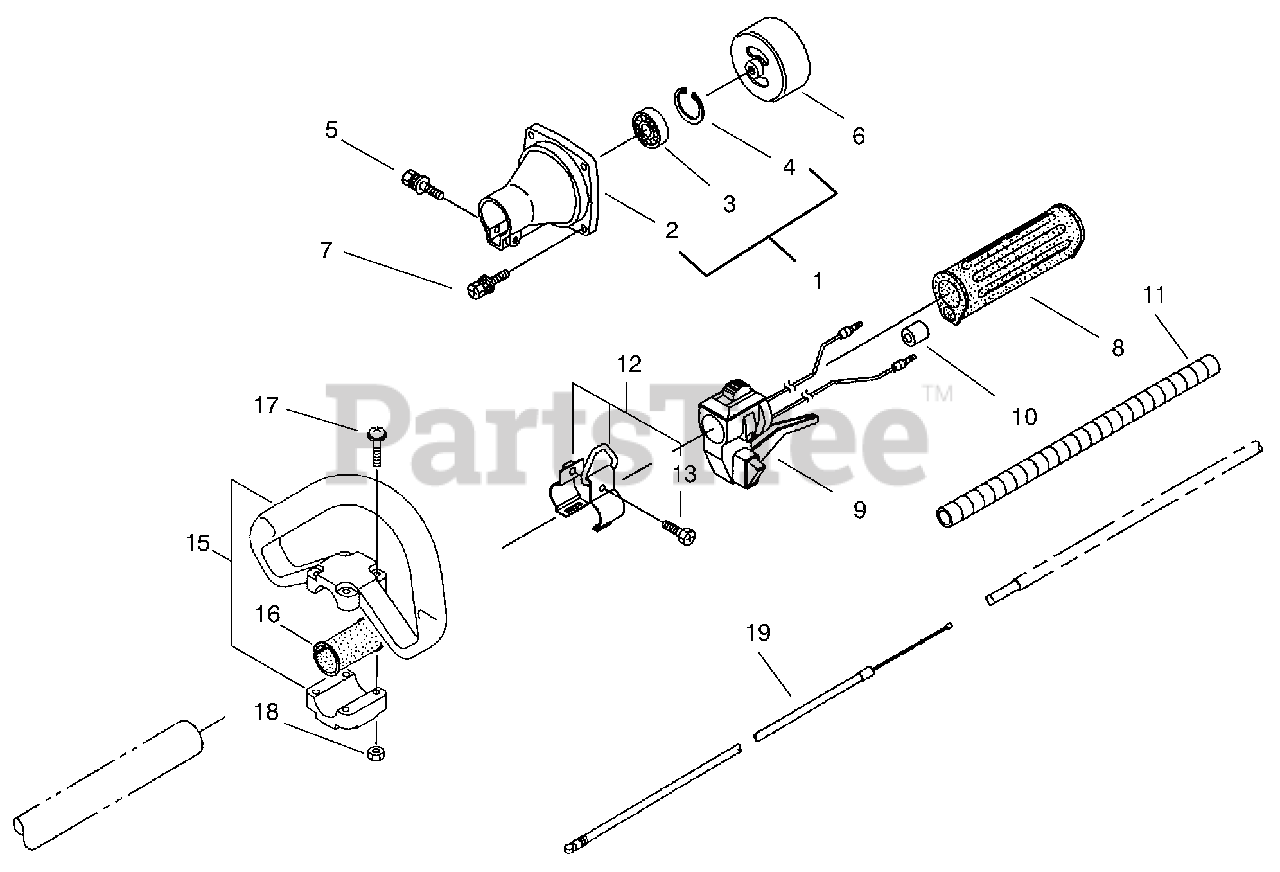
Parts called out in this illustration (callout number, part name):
2	CLUTCH HOUSING
4	RETAINING RING
6	DRUM - CLUTCH
8	GRIP - SHAFT
9	THROTTLE AND SHUTOFF ASSY
10	GUIDE - OUTER
11	DRIVE SHAFT LINER
12	Hanging Bracket Asm (Incl. Ref. #13)
15	HANDLE - LOOP
19	THROTTLE WIRE
